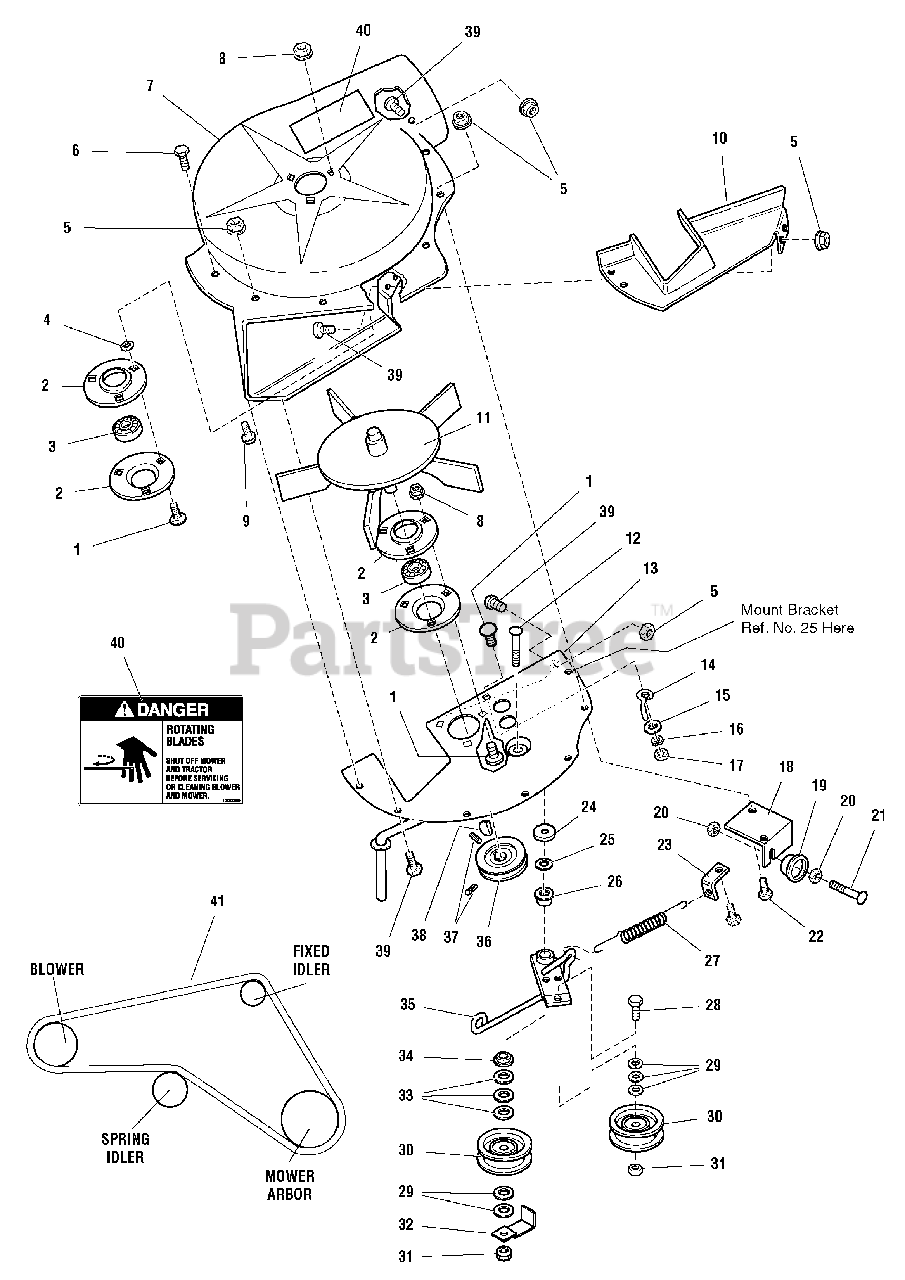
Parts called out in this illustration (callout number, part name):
1	CARRIAGE BOLT, 5/16-18 x 3/4
2	BEARING, Retainer
4	PUSH NUT, 3/8
5	NUT, Hex, Flange Lock, 1/4-20
6	CAPSCREW, Hex, Taptite, 1/4-20 x 1/2
7	FAN HOUSING (Incl. Ref. No. 40)
8	NUT, Flange, Whizlock, 5/16-18
9	SCREW, Washer. Hd., 1/4-18 x 5/8
10	PLATE, Cover
11	FAN ASSY., 5 Blade
12	CARRIAGE BOLT, 3/8-16 x 2-1/4
13	PLATE ASSY.
15	WASHER, Flat
16	WASHER, Spring Lock, 5/16
17	NUT, Hex, 5/16
18	BRACKET ASSY., Turbo
20	NUT, Whizlock, 5/16-18
21	CARRIAGE BOLT, 5/16-18 x 2-1/2
22	CAPSCREW, Hex Hd., 1/4-20 x 3/4
23	BRACKET, Anchor, Spring
24	WASHER, Plain
25	PUSHNUT, 3/8
26	SPACER, Idler Arm
27	SPRING, Tension
28	CAPSCREW, Hex Hd., 3/8-16 x 1-1/4
29	WASHER, Plain
30	IDLER PULLEY ASSEMBLY, 2-3/4 OD
31	NUT, 3/8-16
33	WASHER
34	WASHER
35	LEVER ASSEMBLY, Turbo
36	PULLEY, Driven, 3" OD
37	SETSCREW, Torx Dr, 5/16-18 x 5/16
38	KEY, Woodruff, Modified
39	BOLT, Rd Hd Sq Nk, 5/16-18 x 3/4
40	DECAL, Danger, Blower
